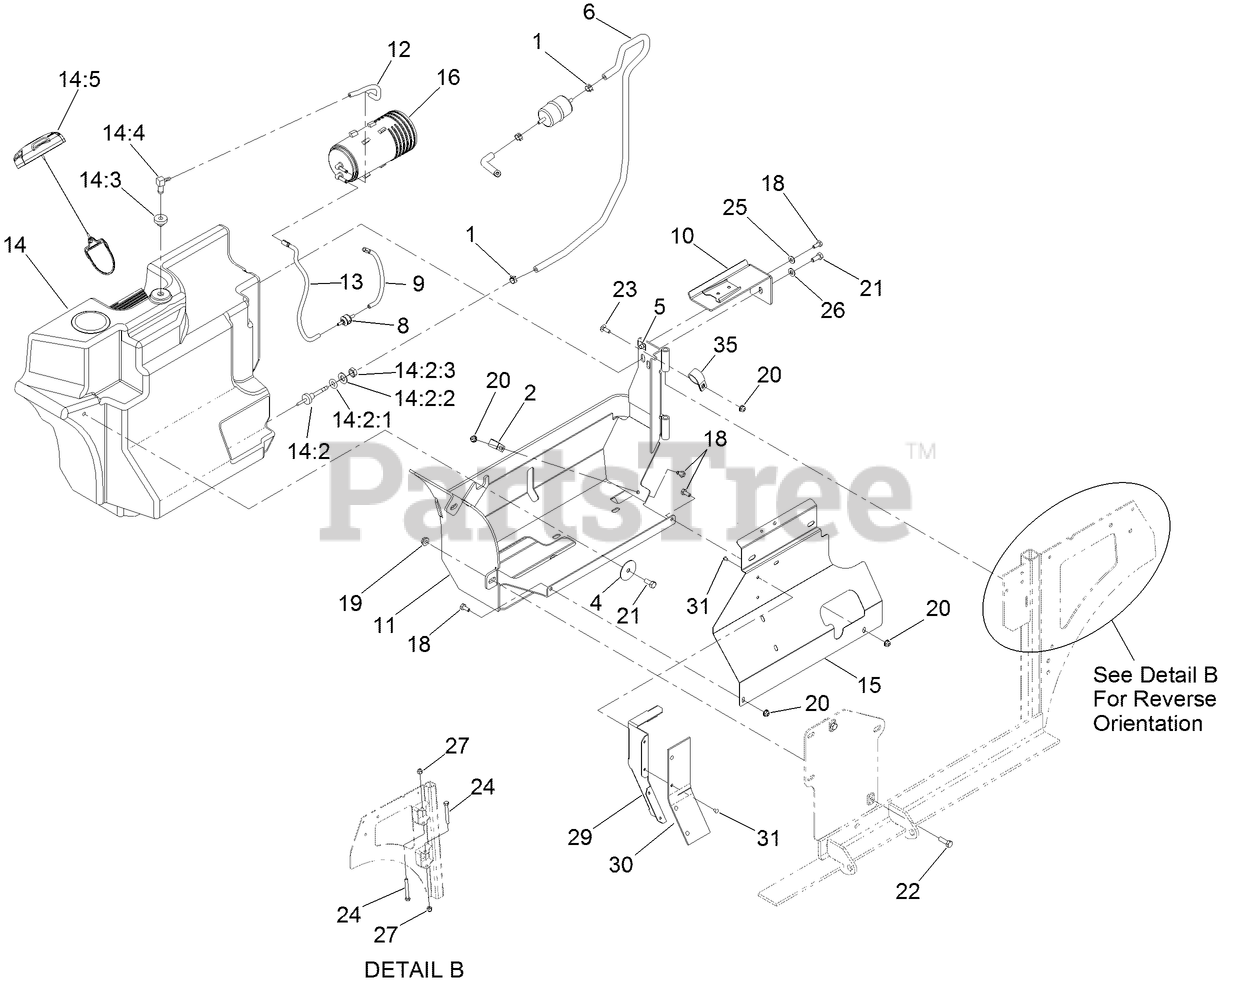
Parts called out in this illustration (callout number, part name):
1	CLAMP-HOSE
2	CLIP-LOOM
4	WASHER
6	HOSE-FUEL
8	VALVE-CHECK, VACUUM
9	HOSE-VENT, FORMED
10	CANISTER BRACKET ASM
11	TANK FRAME ASM
12	HOSE-VENT, FORMED
13	HOSE-VENT, FORMED
14	FUEL TANK ASM
14:2	FITTING-FUEL, BULKHEAD
14:2:1	O-Ring
14:2:2	WASHER-FLAT
14:2:3	NUT-JAM
14:3	BUSHING
14:4	FITTING-90 DEG
14:5	CAP-FUEL, RATCHETING
15	PANEL-TANK SHIELD
16	CANISTER-CARBON, 800CC
18	SCREW-HH
19	NUT-HF
20	NUT-HF
21	SCREW-HH
22	SCREW-HH
23	BOLT-CARR
24	SCREW-HH
25	WASHER-FLAT
26	WASHER-PLAIN
27	NUT-LOCK, NI
29	DEFLECTOR-AIR
30	FLAP-RUBBER
31	RIVET-POP
35	R-CLAMP
